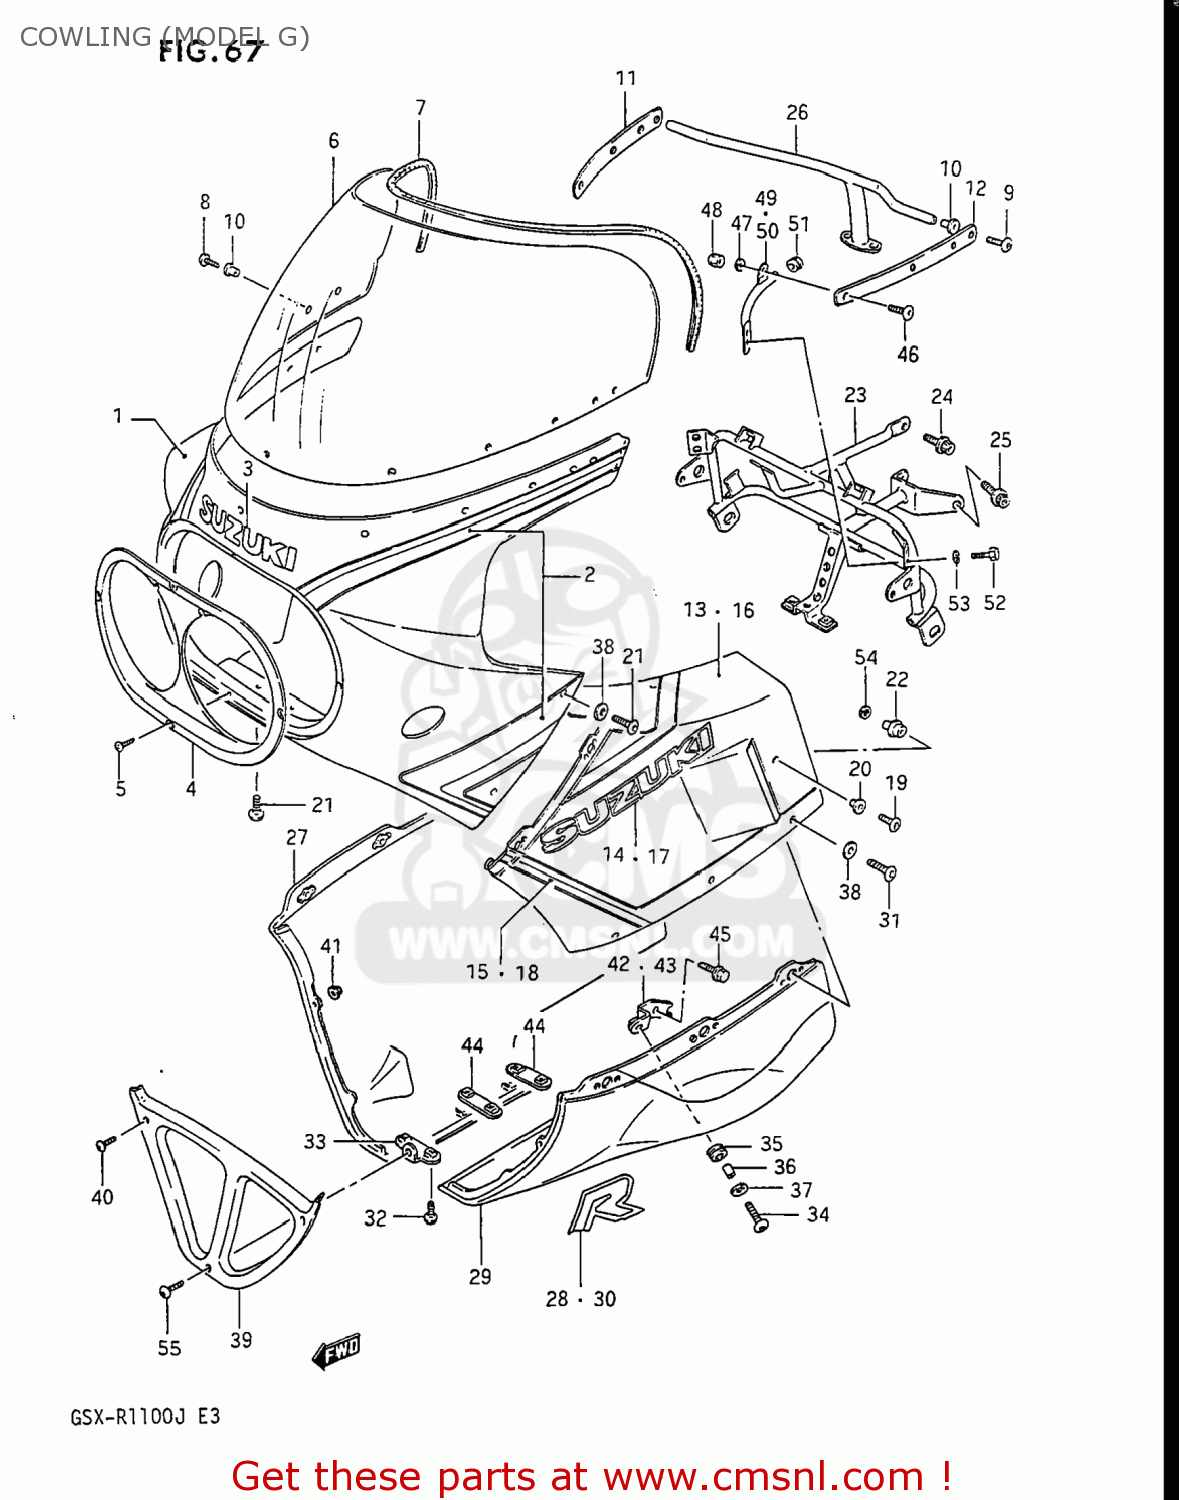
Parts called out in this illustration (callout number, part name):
1	BODY SET,COWLING
2	TAPE SET,BODY COWLING
3	EMBLEM,LEG SHIELD
4	COVER,COWLING FR
5	SCREW
6	WINDSCREEN
7	MOLDING,SCREEN
8	SCREW(5X14)
9	SCREW(5X18)
10	NUT,COWLING SCREEN
11	PLATE,RR VIEW MIRROR,R
12	PLATE,RR VIEW MIRROR,L
13	COVER,COWLING SIDE,RIGHT
14	EMBLEM
15	TAPE SET,COWLING SIDE,RIGHT
16	COVER,COWLING SIDE,LEFT
17	EMBLEM
18	TAPE SET,COWLING SIDE,LEFT
19	SCREW(6X12)
20	WASHER
21	SCREW(6X16)
22	CUSHION,COWLING
23	BRACE,COWLING FR
24	BOLT
25	BOLT
26	BRACE,COWLING BODY RR
27	COVER,COWLING,LOWER,RIGHT
28	EMBLEM
29	COVER,COWLING,LOWER,LEFT
30	EMBLEM
31	SCREW(6X16)
32	SCREW(6X16)
33	BRACE,COWLING LWR COVER
34	SCREW(6X20)
35	CUSHION
36	SPACER
37	WASHER(6.5X18X1)
38	WASHER(6.5X15X1.0)
39	COVER,COWLING,LOWER,FRONT
40	SCREW(5X14)
41	NUT
42	BRACE,COWLING LWR,R
43	BRACE,COWLING LWR,L
44	BRACE,COWLING LWR COVER RR
45	BOLT
46	SCREW(6X16)
47	WASHER,LOCK
48	NUT 6MM
49	BRACE,MIRROR,R
50	BRACE,MIRROR,L
51	PLUG(OD:12)
52	BOLT 6X16
53	WASHER,LOCK
54	WASHER
55	SCREW(6X16)
